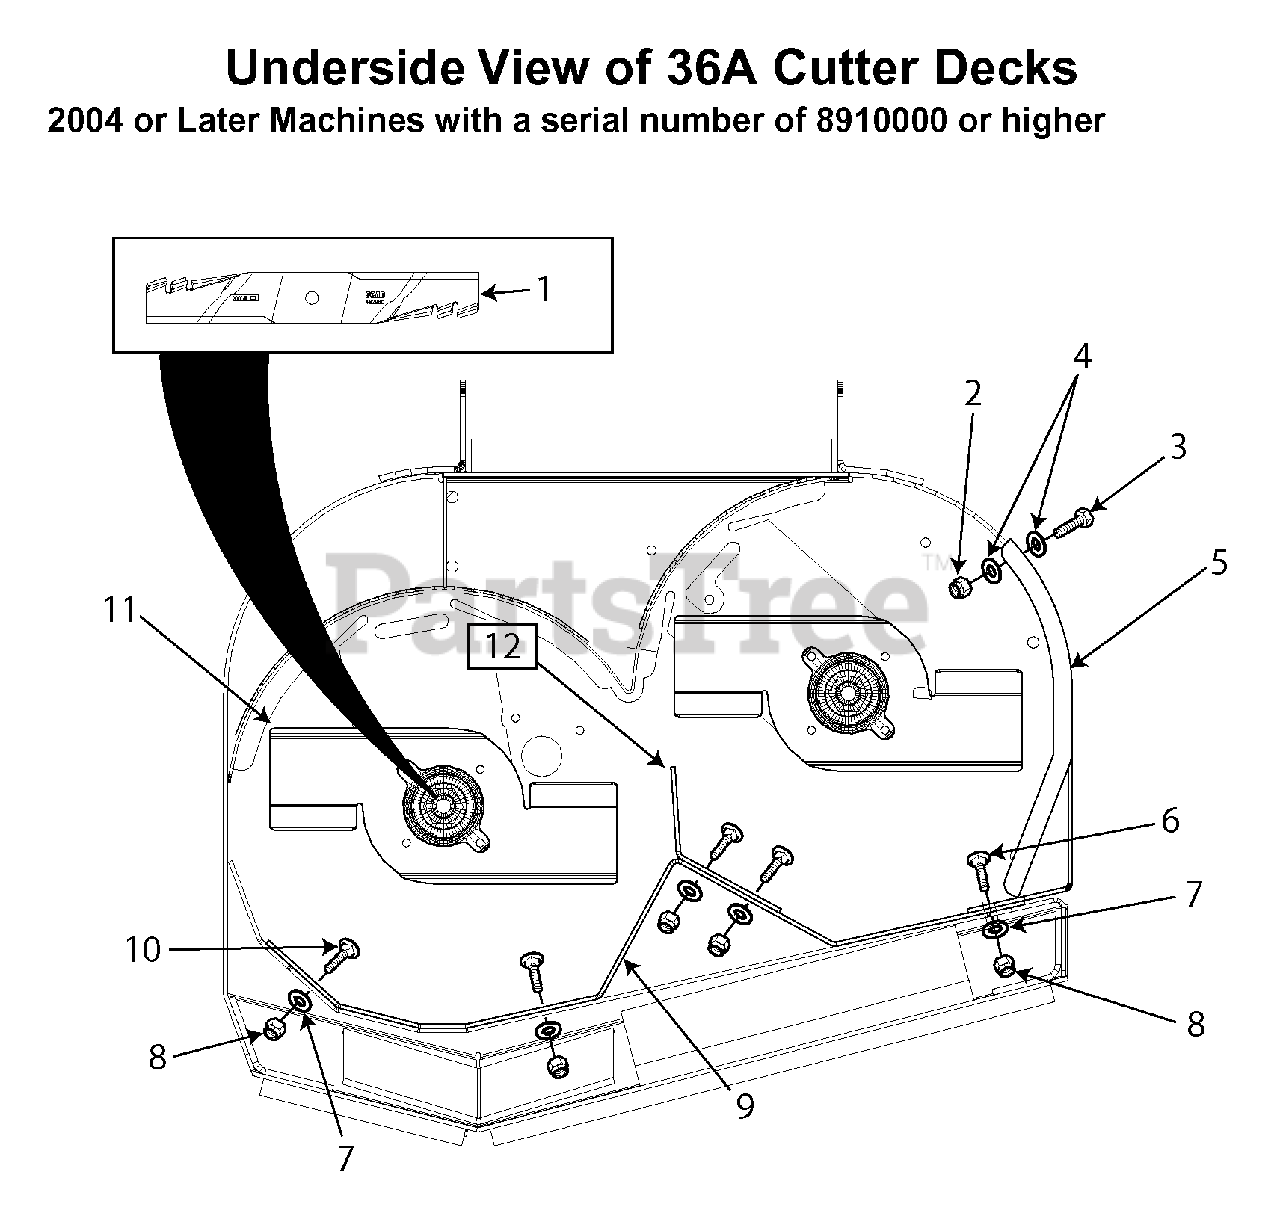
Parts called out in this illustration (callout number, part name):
1	Mulch Baffle L.H.
2	Eliminator Mulch Blades
3	Elastic Stop Nut 5/16-18
4	H.H. Bolt 5/16-18 x 1"
5	Flatwasher 5/16"
6	Mulch Plate
7	Carriage Bolt 3/8-16 x 1-1/4"
8	Flatwasher 3/8"
9	Elastic Stop Nut 3/8-16
10	Mulch Baffle R.H.
11	Divider Plate
12	Carriage Bolt 3/8-16 x 1"
13	Hurricane Plate
